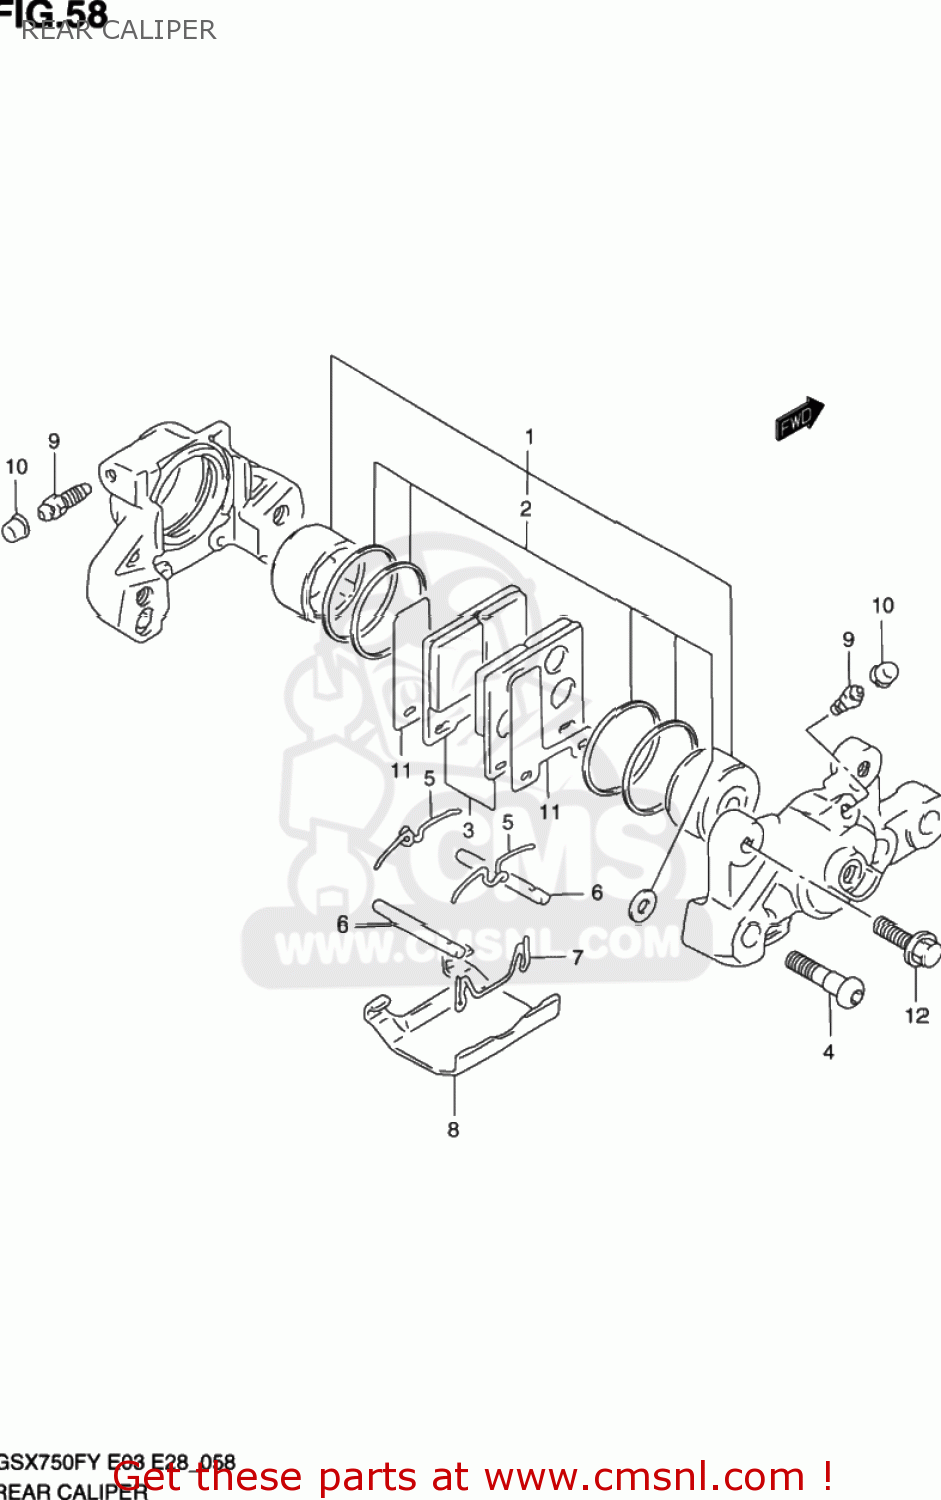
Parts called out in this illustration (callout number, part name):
1	PISTON SET
2	SEAL SET,PISTON
3	PAD SET (NAS)
4	BOLT,HOUSING
5	SPRING
6	PIN,PAD
7	CLIP,PAD PIN
8	COVER
9	BLEEDER
10	CAP,BLEEDER PLUG
11	SHIM
12	BOLT
